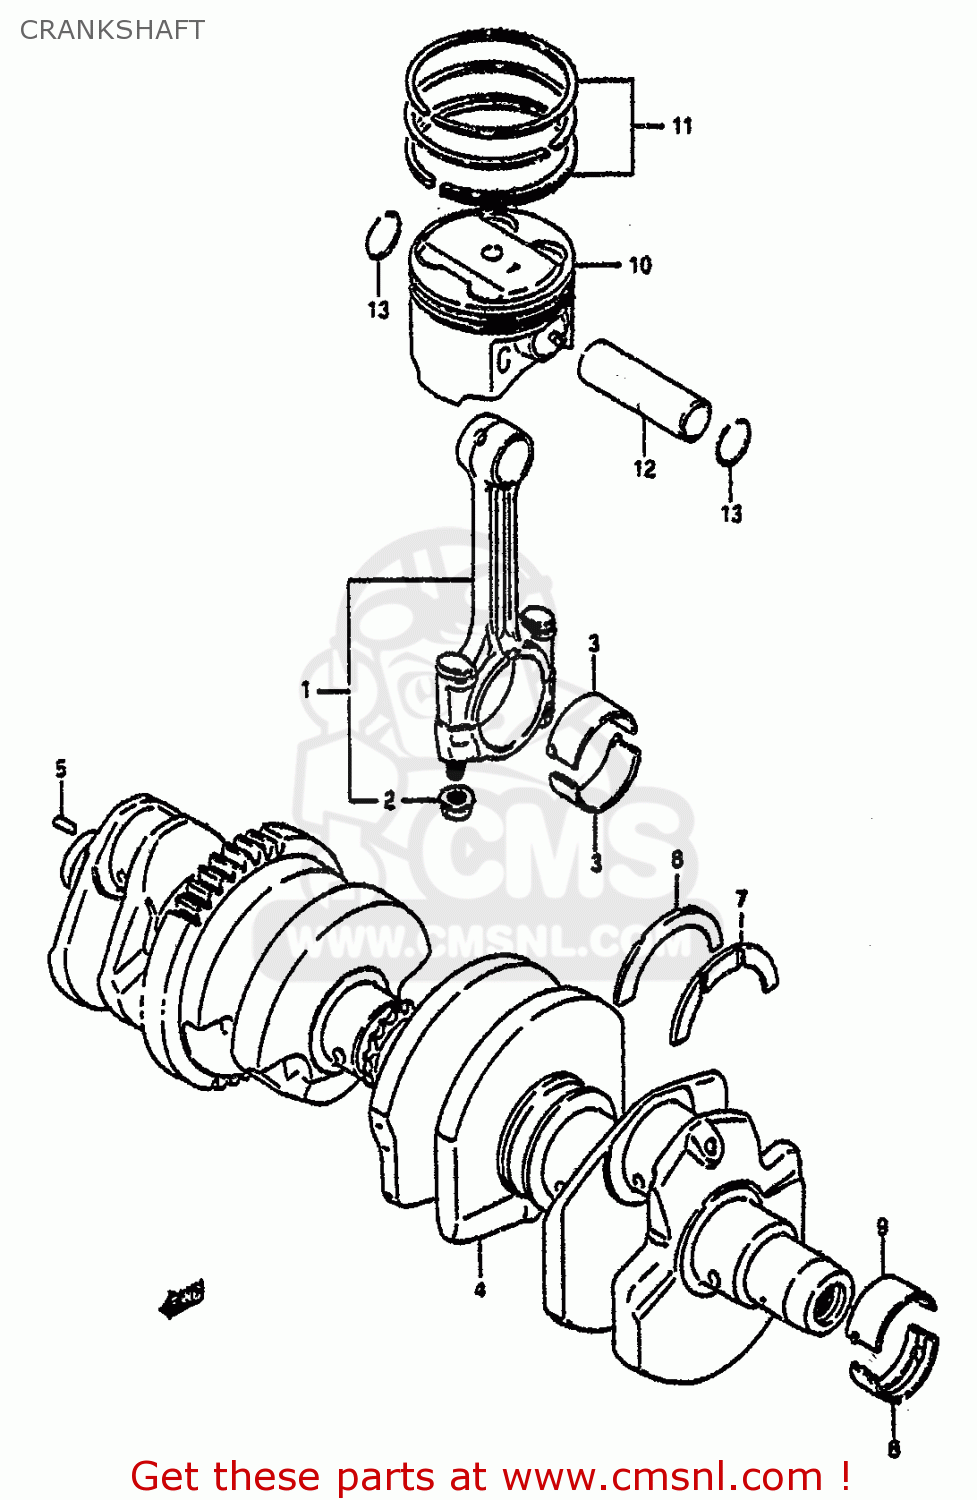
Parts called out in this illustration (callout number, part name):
1	ROD ASSEMBLY,CONNECTING
2	NUT
3	BEARING,CRANK PIN
4	CRANKSHAFT SET
5	PIN
6	BEARING,CRANK THRUST(GREEN)
7	BEARING,CRANK THRUST(RED)
8	BEARING,CRANKSHAFT LWR
9	BEARING,CRANKSHAFT UPR
10	PISTON
11	RING SET,PISTON
12	PIN,PISTON
13	CIRCLIP,PISTON PIN
